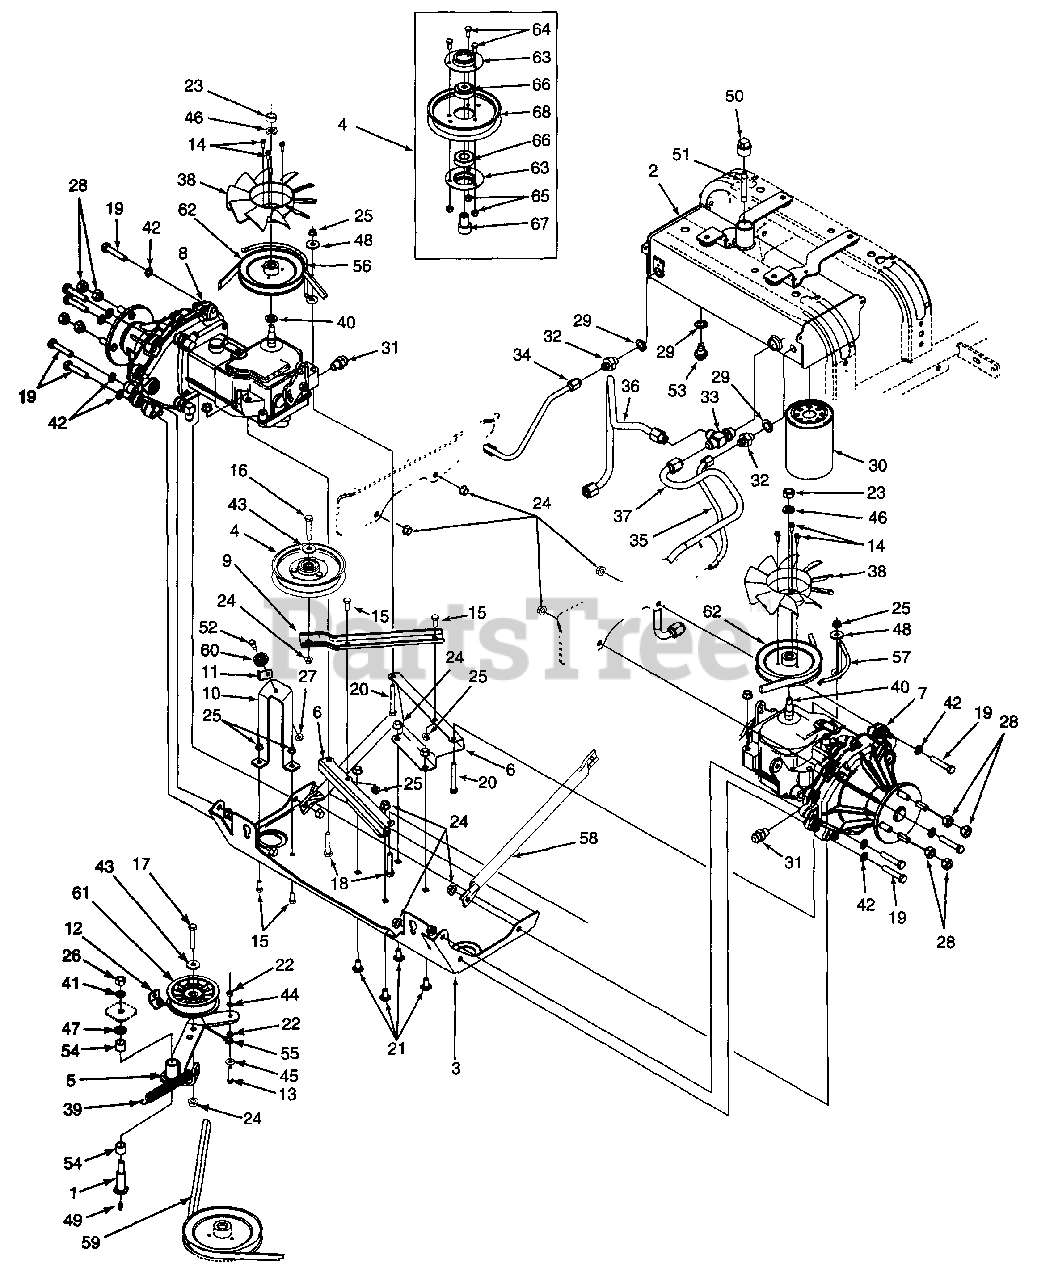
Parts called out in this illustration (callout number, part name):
1	Shoulder Bolt, Special
2	Tank Ass'y, Hydraulic
3	Plate Ass'y, Skid
4	Pulley Ass'y, Idler 5.0 in
8	Transmission Ass'y LH
11	Bracket, Cable Retainer
12	Bracket, Cable Mtg
13	Screw, Hex Cap 1/4-28 x 1.25 GR5
14	Screw, Hex Wash. Hd. Tapp #12-24 x .62
15	Screw, Hex Cap 5/16-18 x .75 GR5
16	Screw, Hex Cap 3/8-16 x 2-1/4 GR5
17	Screw, Hex Cap 3/8-16 x 1-3/4 GR5
18	Screw, Hex Cap 5/16-18 x 2.0 GR5
19	Screw, Hex Cap 3/8-16 x 2.0 GR5
20	Screw, Hex Cap 5/16-18 x 2.50 GR5
21	Bolt, Carriage, 3/8-16 x .75
22	Nut, Hex, 1/4-28
23	Nut, Hex, 1/2-20
24	Nut, Hex Flange Lock, 3/8-16
25	Nut, Hex Flange Lock, 5/16-18 GR5
26	Nut, Hex, 7/16-14
27	Nut, Hex Lock, 1/4-20
28	Nut, Lug, 7/16-14
29	Seal, Drain Plug
30	Filter Element, Oil
31	Fitting, Connector, 1/2 x 3/8
32	Fitting, Connector
33	Fitting, Tee, 1/2 x 1/2 x 3/4
34	Tube, Inlet LH
35	Tube, Inlet RH
36	Tube, Outlet LH
37	Tube, Outlet RH
38	Fan, 10 Blade
39	Spring, Extension
41	Washer, Lock, 7/16
42	Washer, Flat, .406 x .75 x .06
43	Washer, Flat, .385 x 1.0 x .135
44	Washer, Lock, 1/4 ID
45	Washer, Flat, .283 x .75 x .030
46	Washer, Lock, 1/2
47	Washer, Flat, .469 x .875 x .105
48	Washer, Flat, 5/16 x .934 x .100
49	Fitting, Grease
50	Plug, Pipe, w/ Vent 3/4 NPTF
51	Tube, Dipstick
52	Bolt, Shoulder, 1/4-28: .375
53	Plug, Oil Drain
54	Bearing, Sleeve, .628 x .75 x .625
55	Cable, Declutching
56	Rod, Belt Retaining RH
57	Rod, Belt Retaining LH
58	Strut, Frame
59	V-Belt, Transmission Drive A-Section x 54.24 Lg
60	Cable Roller
61	Pulley, Flat Idler 3.5 in
62	Pulley, Transmission
63	Cup, Bearing
64	Screw, Hex Cap, 1/4-20 x .62 GR5
65	Nut, Hex Insert Lock, 1/4-20
66	Bearing, Ball
67	Spacer, Idler
68	Pulley, Idler 5.0 in
